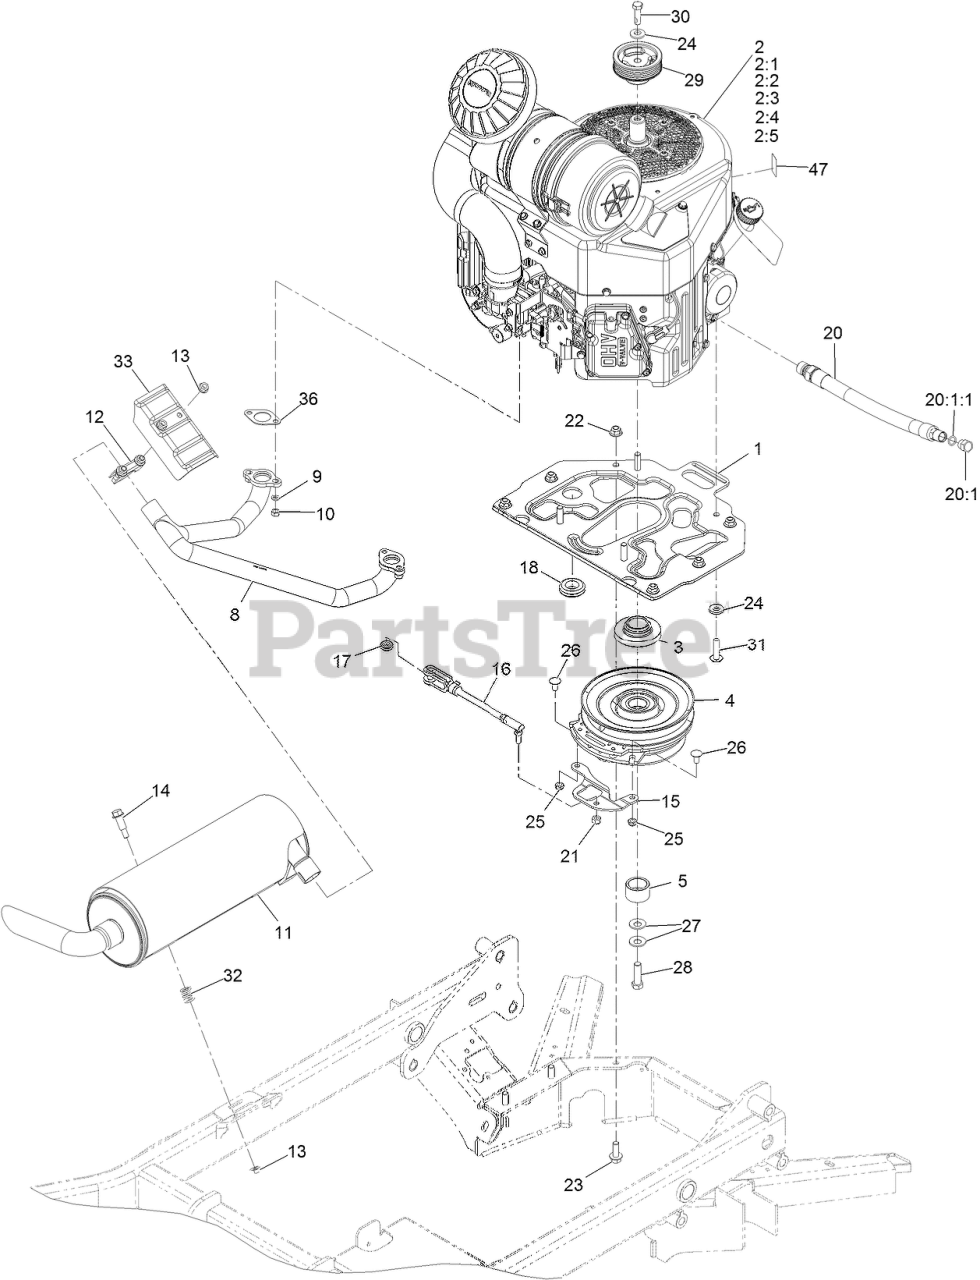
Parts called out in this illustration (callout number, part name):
1	Plate, Engine
2:1	Kawasaki 49065-7007 Engine Oil Filter
2:2	Kawasaki 49019-0031 Fuel Filter
2:3	Kawasaki 92070-7004 Plug-Spark Bpr4ES
2:4	Kawasaki 11013-7045 Pre-Filter
2:5	Kawasaki 11013-7044 Air Filter
3	Spacer, Clutch 1.13
5	Spacer, Clutch
8	Header, Kawaswaki
9	WASHER-LOCK
11	Muffler, 5"
12	CLAMP-MUFFLER
14	Bolt-Shoulder
15	Strap, Clutch
16	ASM, CLUTCH ANCHOR
17	GROMMET
18	GROMMET
20	ENGINE OIL DRAIN HOSE ASM
20:1	PLUG-HH
20:1:1	O-RING
21	NUT-LOCK
22	NUT-HF, NI
23	SCREW-HHF 3/8-16 X 1
24	WASHER-BELLEVILLE
25	NUT-LOCK, NI
26	SCREW-CARR
27	WASHER-SPRING
28	SCREW-HH 7/16-20 X 1 1/2 W/LOCTITE
29	PULLEY, CRANK
30	Screw-HH, Patch
31	SCREW-BHTF
33	Shield, Heat
36	GASKET-EXHAUST
47	Decal-10W-50 Oil
